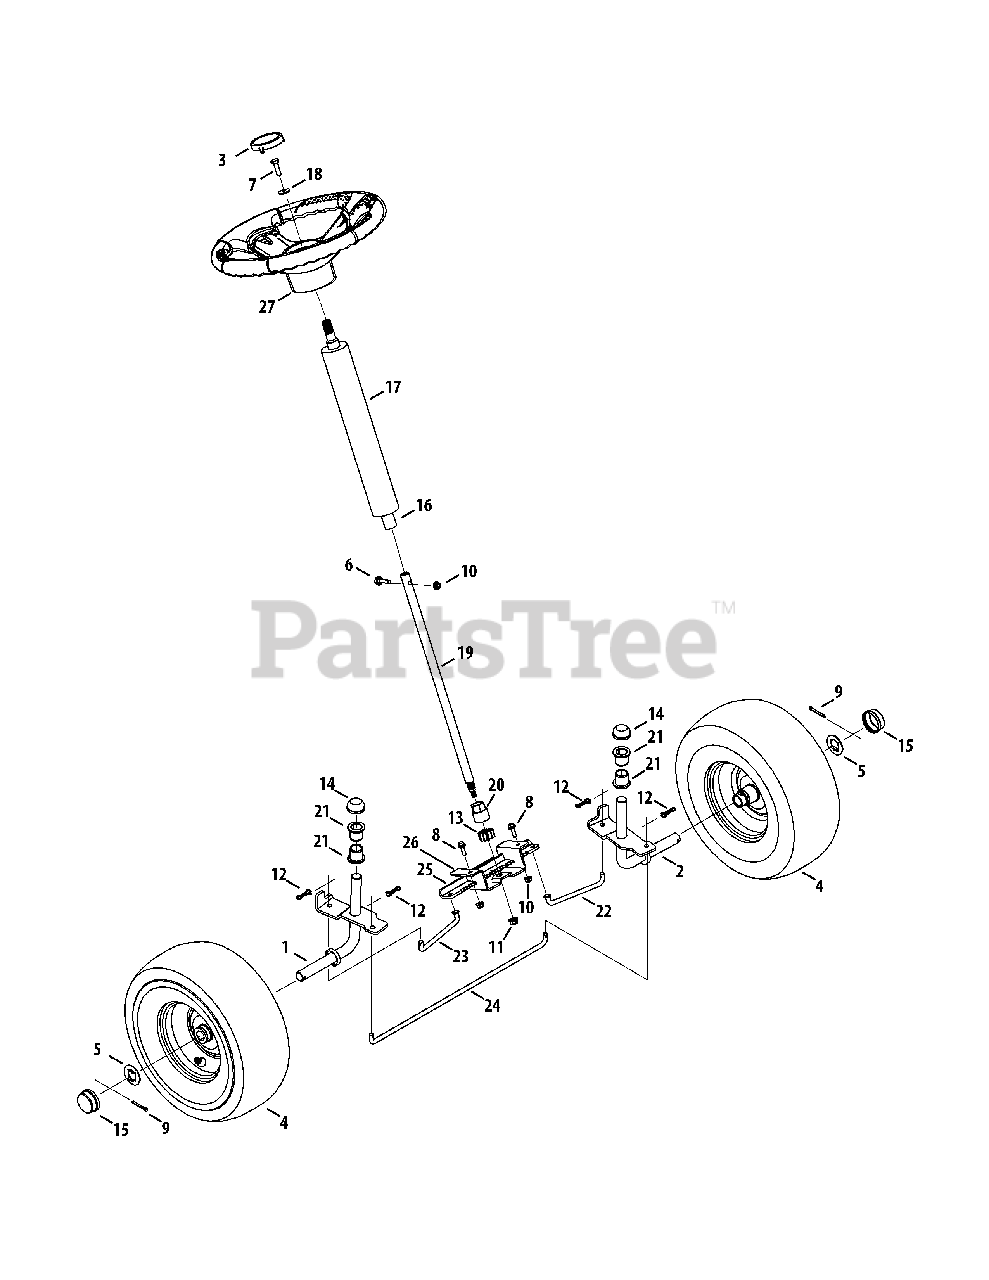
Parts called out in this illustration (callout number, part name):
1	Front Axle Assembly, RH
2	Front Axle Assembly, LH
3	Sprig Cap
4	Complete Wheel Assembly
5	Washer, .781 x 1.59
6	Shoulder Screw, .375 x .148 x 1/4-20
7	Hex Head Screw, 5/16-18:1.00
8	Carriage Screw, 1/4-20, .75
9	Cotter Pin, 5/32 x 1.25
10	Flange Lock Nut, 1/4-20
11	Flange Lock Nut, 3/8-16
12	Bow-Tie Cotter Pin, 72
13	Steering Pinion Gear
14	Push Cap, 3/4
15	Hub Cap
16	Tube Assembly, Non-Telescoping
17	Steering Sleeve
18	Bevel Washer, .340X.872X.060
19	Steering Shaft, .625 OD X 18.03
20	Hex Flange Bearing, 5/8
21	Flange Bearing, .760 X .941 X 1.0
22	Steering Rod, LH
23	Steering Rod, RH
24	Front Tie Rod
25	Steering Rack Plate
26	Lower Steering Bearing
27	Steering Wheel, Std. Grip
